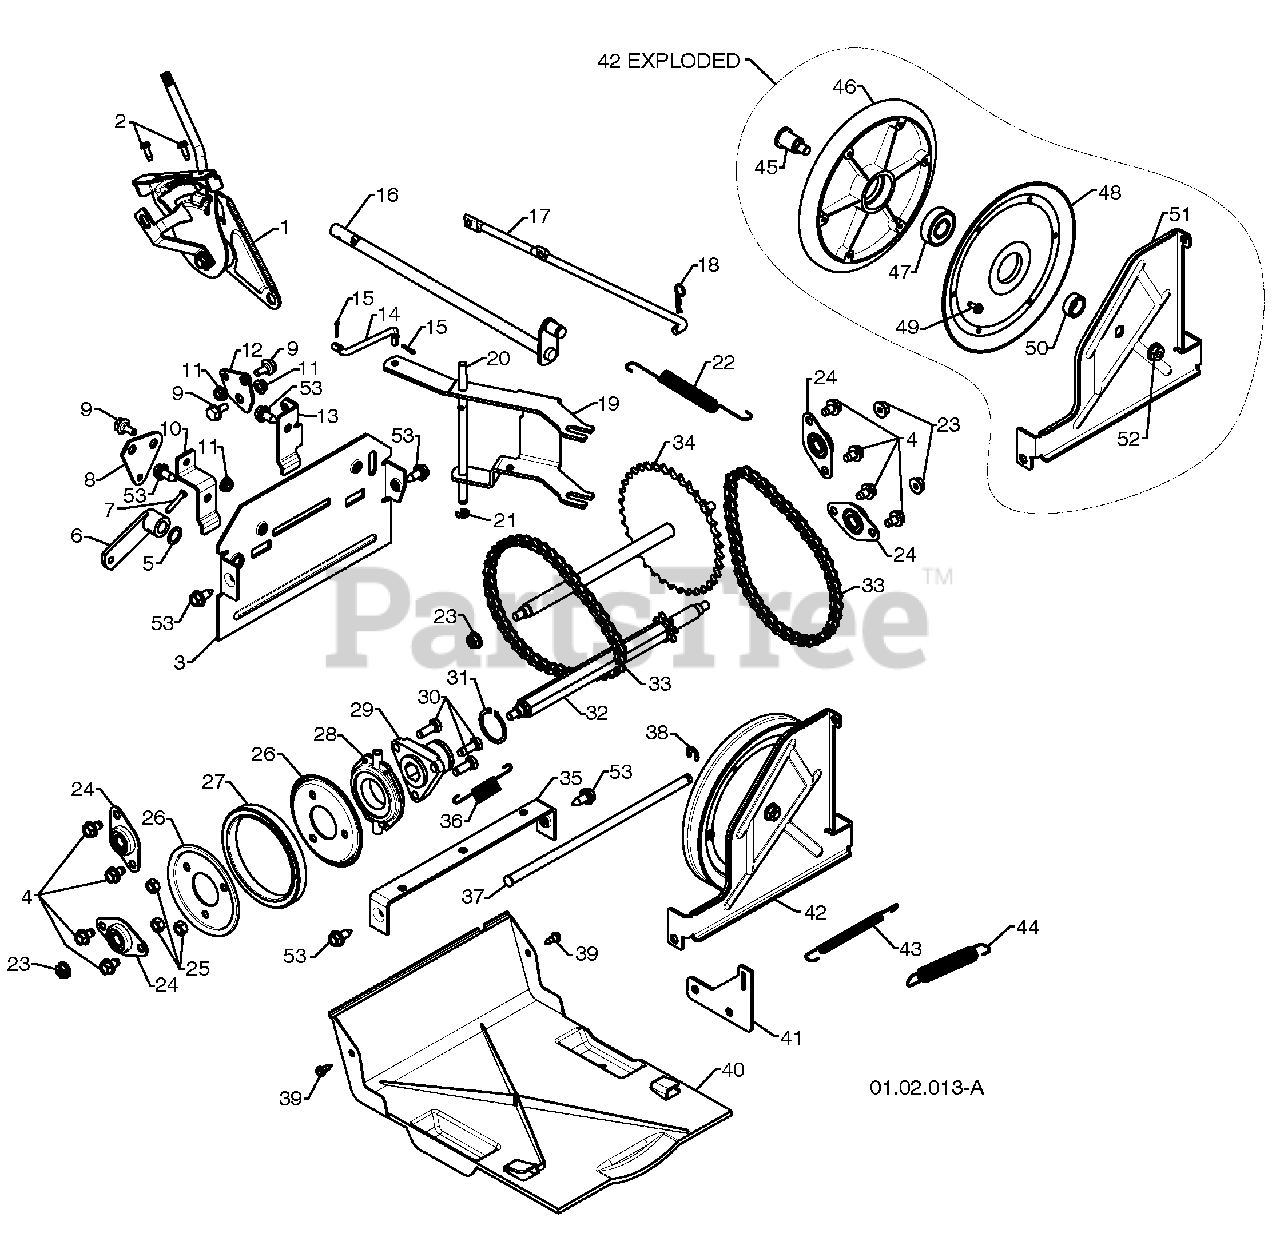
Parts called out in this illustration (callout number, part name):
1	SPEED SELECTOR ASSEMBLY
2	SCREW 10-24 X .625
3	END PLATE
4	SCREW 5/16-18 X .50
5	WASHER
6	CONTROL ARM
7	CLEVIS PIN
8	SHIFTER PLATE
9	SHOULDER BOLT
10	SHIFTER BRACKET
11	NUT 1/4-20
12	CLUTCH PLATE
13	CLUTCH BRACKET
14	SHIFTER LINK
15	RETAINER
16	CONTROL SHAFT
17	CLUTCH ROD
18	RETAINER
19	SHIFTER YOKE
20	PIVOT ROD
21	RETAINER
22	RETURN SPRING
23	NUT 5/16-18
24	BEARING
25	NUT 5/16-18
26	RUBBER WHEEL PLATE
27	RUBBER RING
28	BEARING
29	WHEEL HUB
30	SCREW 5/16-18-.875
31	RETAINER RING
32	SPROCKET SHAFT
33	CHAIN
34	SPROCKET WELDMENT
35	SHIFTER BRACKET
36	SPRING
37	PLATE PIVOT ROD
38	E-RING .375
39	SHOULDER SCREW
40	BOTTOM PAN
41	SPRING BRACKET
42	DRIVE PLATE ASSEMBLY
43	IDLER SPRING
44	IDLER SPRING
45	PULLEY SHAFT
46	DRIVE PLATE
47	BEARING
48	PULLEY HALF
49	SCREW 10-24 X .50
50	SPACER BEARING
52	NUT 3/8-16
53	SCREW 5/16-18 X .750
